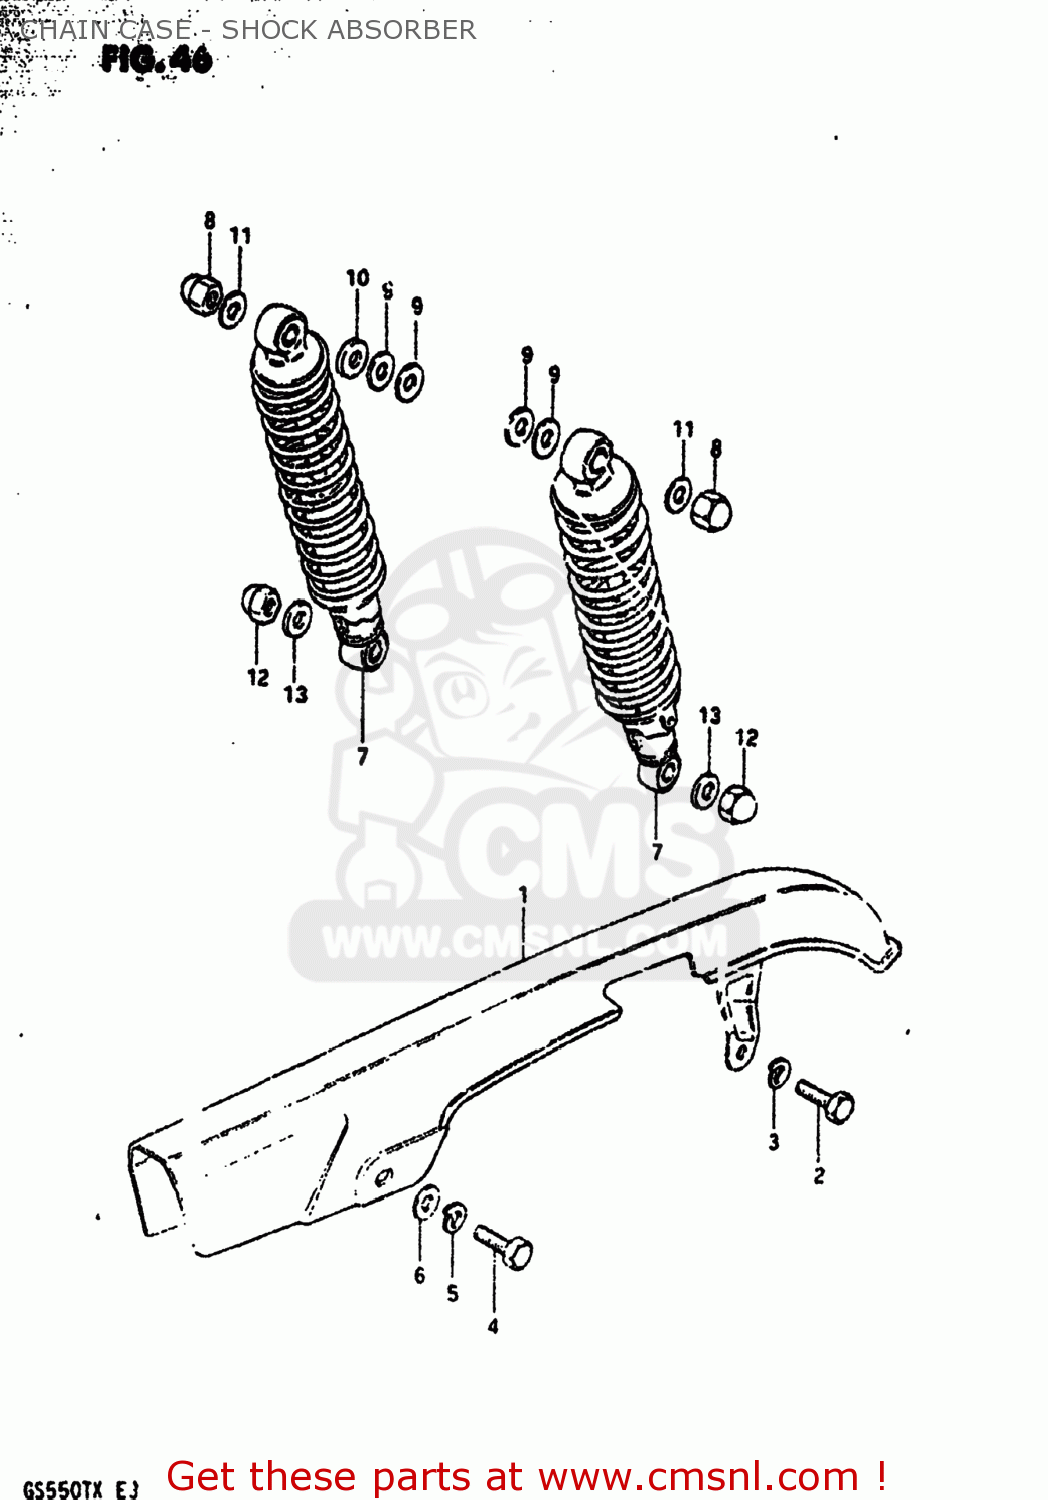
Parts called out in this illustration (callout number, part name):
1	CASE,CHAIN
2	BOLT
3	LOCK WASHER
4	BOLT
5	LOCK WASHER
6	WASHER
7	ABSORBER ASSEMBLY,REAR SHOCK
8	NUT
9	WASHER
10	WASHER (12.5X24X3.2)
11	WASHER
12	NUT, LOWER LH
13	WASHER
